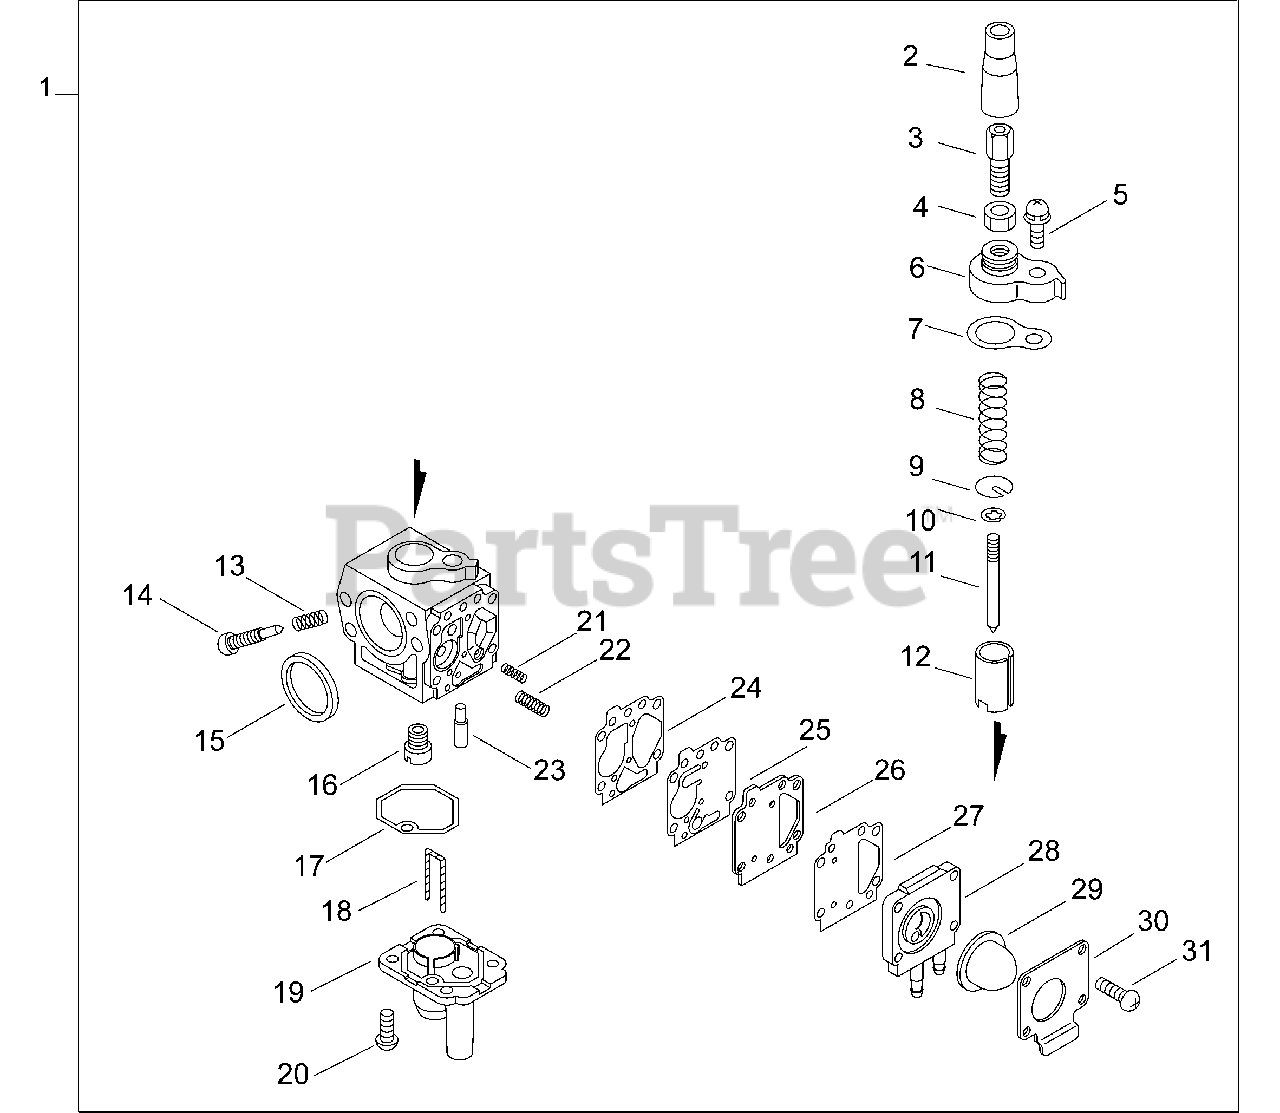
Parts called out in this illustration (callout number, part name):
1	CARBURETOR
2	CAP, RUBBER
3	ADJUSTER, CABLE
4	NUT, LOCK
5	SCREW 5×16
6	COVER, TOP
8	SPRING, THROTTLE
9	WASHER, SPRING SUPPORT
11	NEEDLE, JET
12	VALVE, THROTTLE
14	SCREW, IDLE ADJUST
15	RING, PACKING
16	JET, MAIN #44
17	GASKET, CHAMBER
18	WIRE, DRAIN
19	CHAMBER, FLOAT
20	SCREW 3×10
23	NEEDLE, JET
24	GASKET, PUMP
25	DIAPHRAGM, FUEL PUMP
26	PLATE, PUMP
27	GASKET, FUEL PUMP
28	COVER, PUMP
29	BULB, PURGE
30	PLATE, PUMP
31	SCREW 3×14
